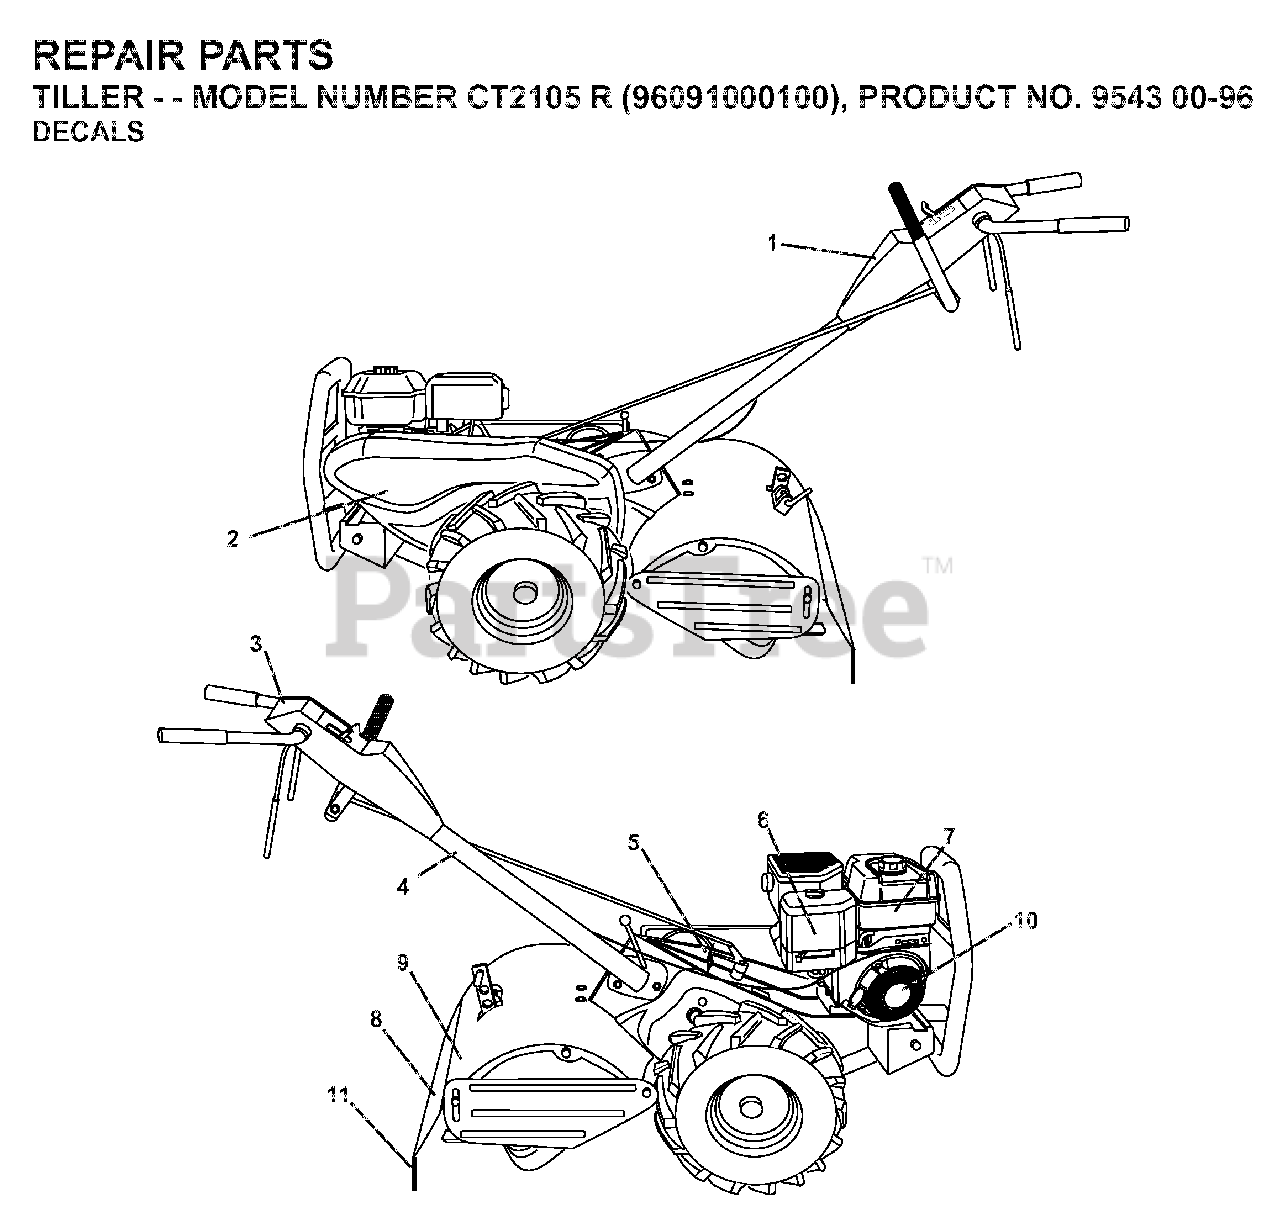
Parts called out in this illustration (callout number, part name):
5	DECAL.SHIFT.INDICATOR.TILLER
9	DECAL EUROPE STANDARD CE
10	DECAL.REWIND
